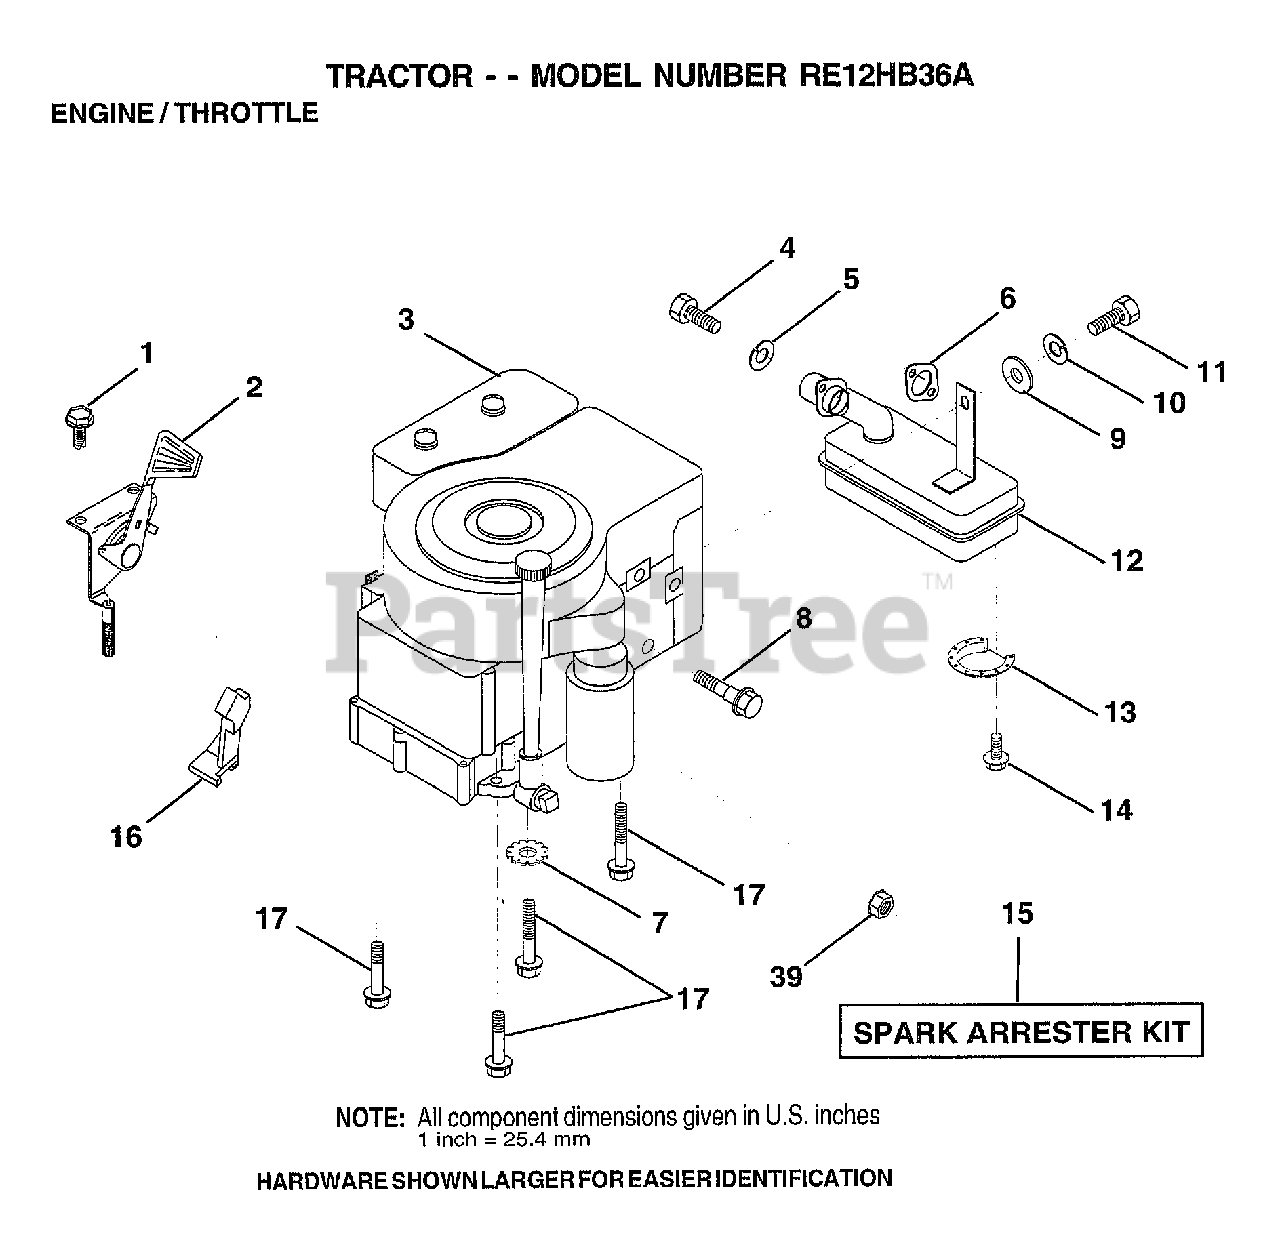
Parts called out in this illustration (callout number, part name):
1	SCREW LT
4	SCREW
5	LOCKWASHER
7	LOCKWASHER
8	BOLT T
10	LOCKWASHER
12	MUFFLER
13	DEFLECTOR.222573
16	"STOP,DASH THROTT"
17	SCREW LT
39	NUT
